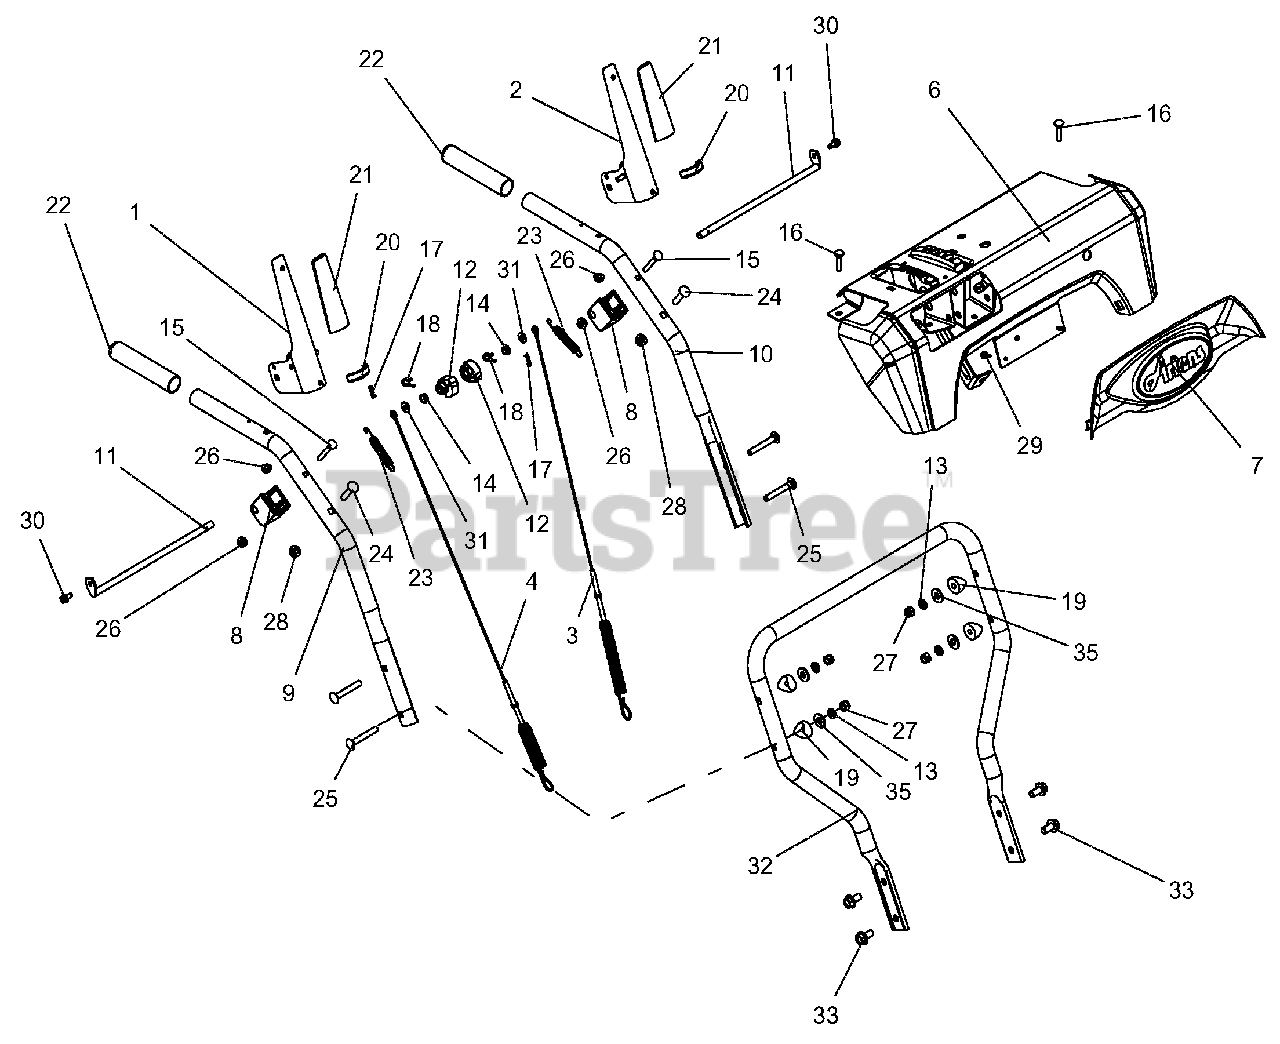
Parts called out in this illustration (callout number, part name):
1	LEVER, CLUTCH-RH
2	LEVER, CLUTCH-LH
3	CABLE, UPPER TRACTION
4	CABLE, AUGER (DELUXE & PRO)
6	CONTROL PANEL W/DECAL, CRANK
7	DASH BEZEL, ARIENS LOGO - PRO
8	BLOCK, CLUTCH PADDLE
9	HANDLEBAR, UPPER - RH
10	HANDLEBAR, UPPER - LH
11	ROD, PADDLE MOUNT - PRO
12	CAM, INTERLOCK
13	WSHR-LK .312X.097 HVY YWZC
14	BUSHING, POLYLINER-.38 SNAPIN
15	BLT-RDHDXLSQNK .25-20X2.0 G5YZ
16	BLT-RDHDXLSQNK.25-20X1.25 G5ZC
17	PIN-HAIR INT .06X.18X.77
18	PIN, SPRING CLIP
19	SPACER, HANDLEBAR
20	EDGING, CLUTCH PADDLE - 2.00"
21	CLUTCH PADDLE SLEEVE - GRAY
22	HANDLE GRIP
23	SPRING, EXTENSION
24	@BLT-RDHDSQNK .31-18X1.50 G5YZ
25	@BLT-RDHDSQNK .31-18X2.25 G5YZ
26	@NUT-LK-CTR-FLG .25-20 YWZC
27	@NUT-LK-NYL .312-18 YWZC
28	@NUT-LK-TOP-FLG .31-18 YWZC
29	SCR-TAP #10X.50 BOSS INDHXHD
30	SCR-TAP .25-20X.50 HWH TR YWZ
31	@WSHR-FL-STL.281X.62X.065 YWZC
32	HANDLEBAR, LOWER - DELUXE
33	BLT-SERHFWH .38-16X.75 YWZC
35	@WSHR-FL-STL.38X.875X.083 YWZC
